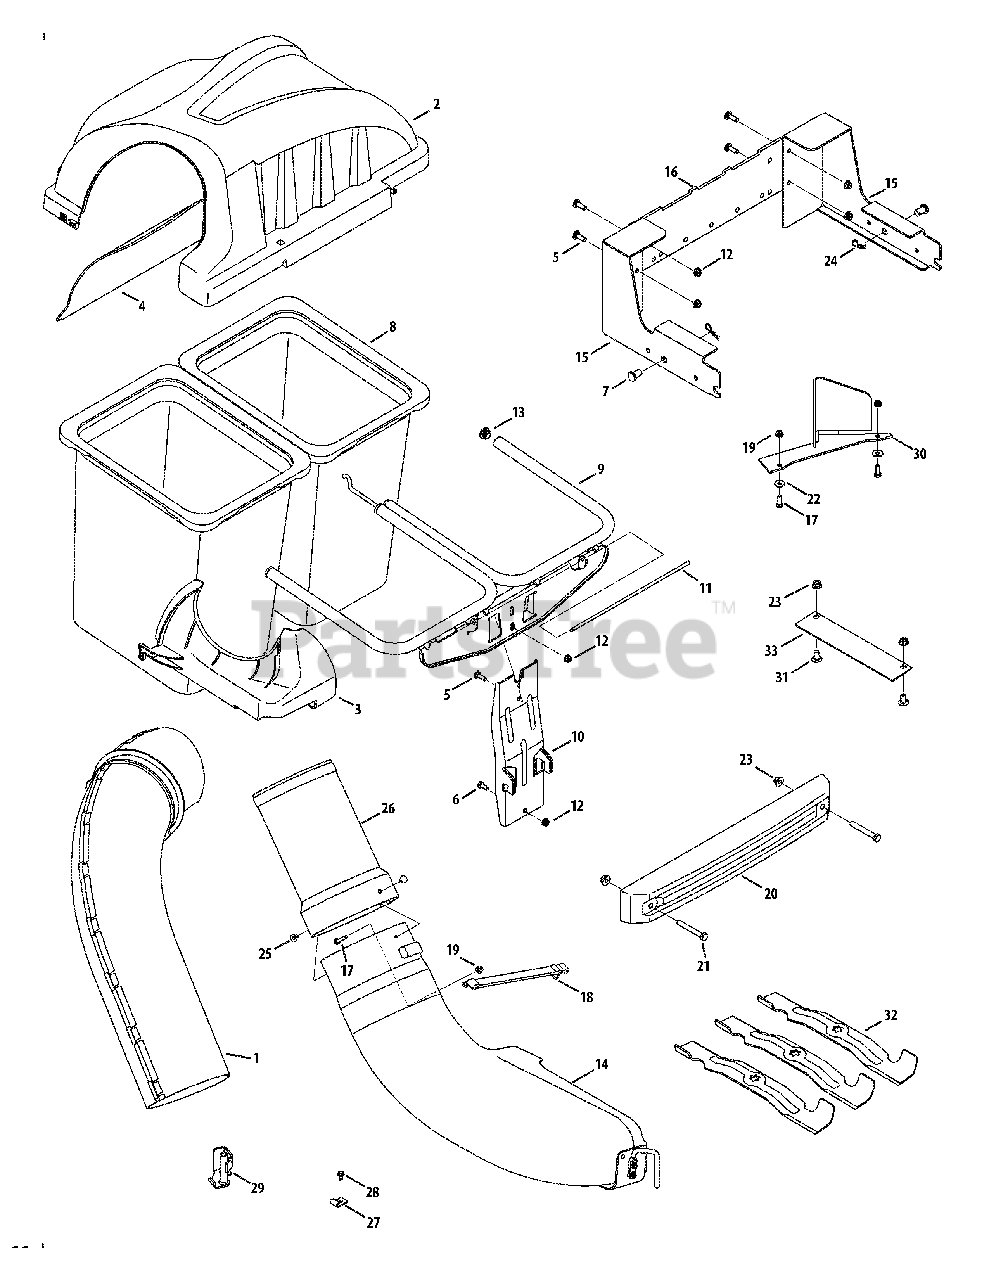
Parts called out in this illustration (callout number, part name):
1	Upper Chute Assembly
2	Twin Bagger Cover Assembly
3	Upper Chute Support
4	Bagger Cover Screen
5	Carriage Screw, 5/16-18 x 1.00"
6	Hex Head Screw, 5/16-18 x .75"
7	Clevis Pin, .50" Dia.
8	Grass-bag Assembly
11	Cover Hinge Pin
12	Flange Lock Nut, 5/16-18
14	Discharge Chute Elbow
15	RZT Hitch Bracket Kit (RH & LH)
16	Universal Cross Bracket
17	Hex Head Screw, 1/4 - 20 x .75
18	Chute Strap
19	Flange Lock Nut, 1/4 - 20
20	Bagger Weight
21	Hex Head Screw, 3/8 - 16 x 2.75
22	Belleville Washer
23	Flange Lock Nut, 3/8 - 16
24	Cotter Pin, .080 x 1.5625 Internal
25	Ratchet Clip, .250
26	Bagger Chute Adapter, 8 x 13.5
27	Retainer Hook Bracket
28	Self-Tap Screw, 1/4-20 x .500
29	Chute Stop Bracket
30	Deck Baffle, 50"
31	Carriage Bolt, 3/8-16 x 1.00
32	Bagging Blade, 17.90 Lg. Star
33	Chute Discharge Plate
